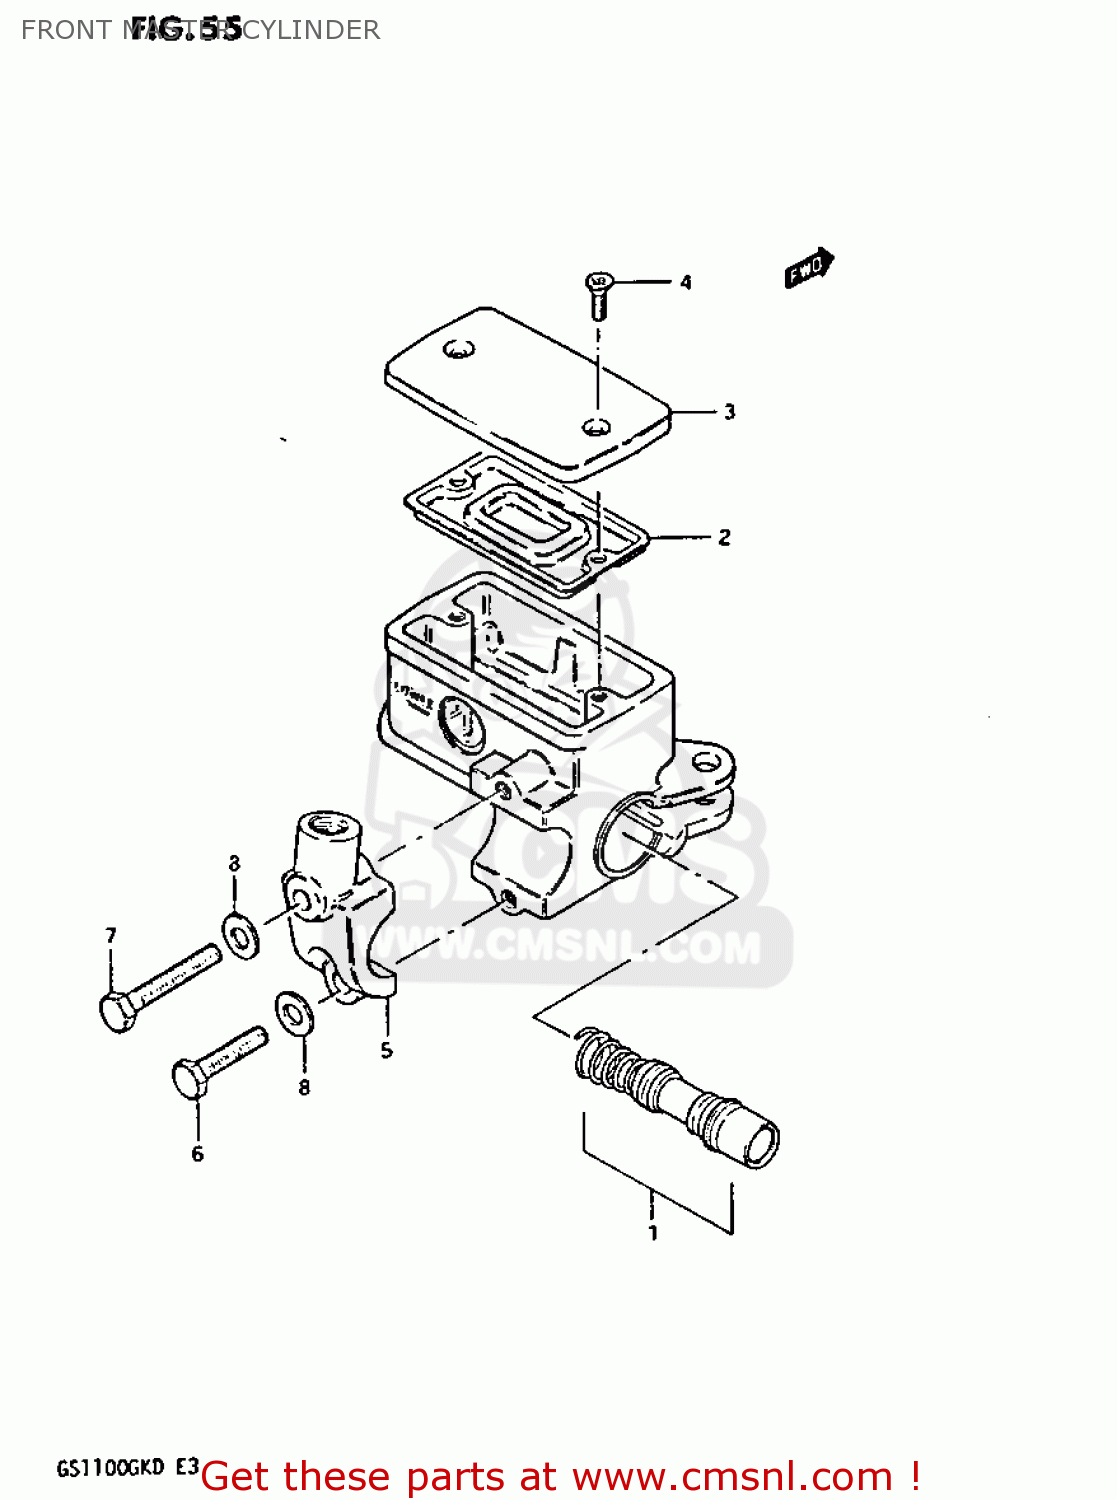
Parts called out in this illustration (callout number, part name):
1	PISTON & CUP SET
2	3
3	CAP
4	SCREW
5	HOLDER
6	BOLT 6X40
7	BOLT
8	WASHER
